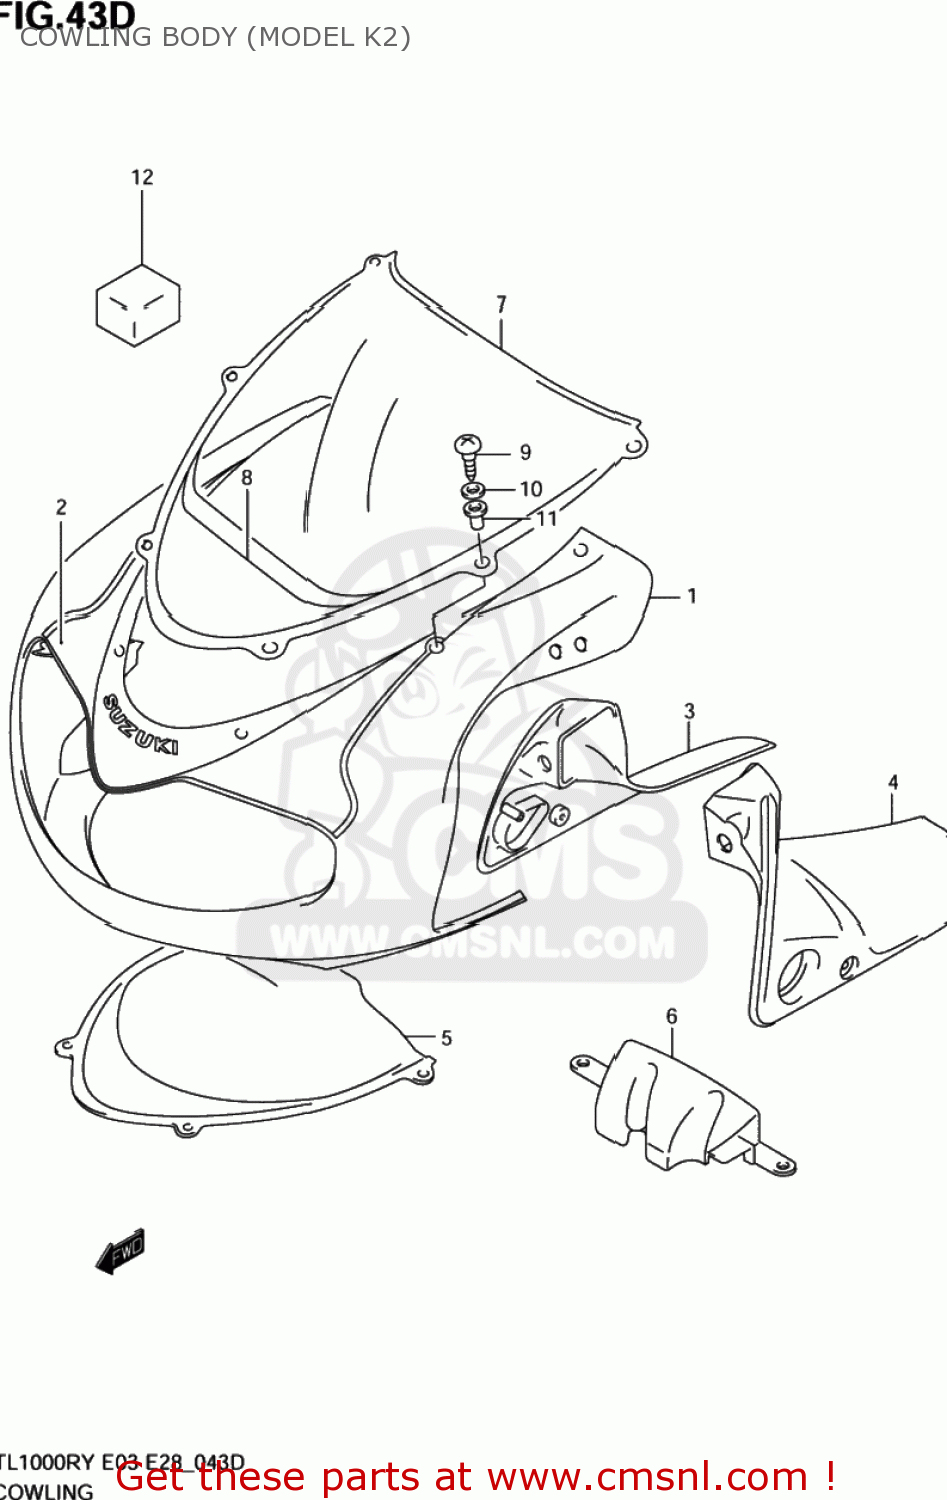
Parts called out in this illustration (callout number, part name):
1	COWLING ASSY,BODY
2	TAPE,FR
3	PANEL,SIDE,R(BLACK)
4	PANEL,SIDE,L(BLACK)
5	COVER,BODY COWLING
6	COVER,COWLING FR LWR
7	WINDSCREEN
8	TAPE,WINDSCREEN
9	SCREW(5X14)
10	WASHER
11	NUT
12	CUSHION,BODY COWLING
